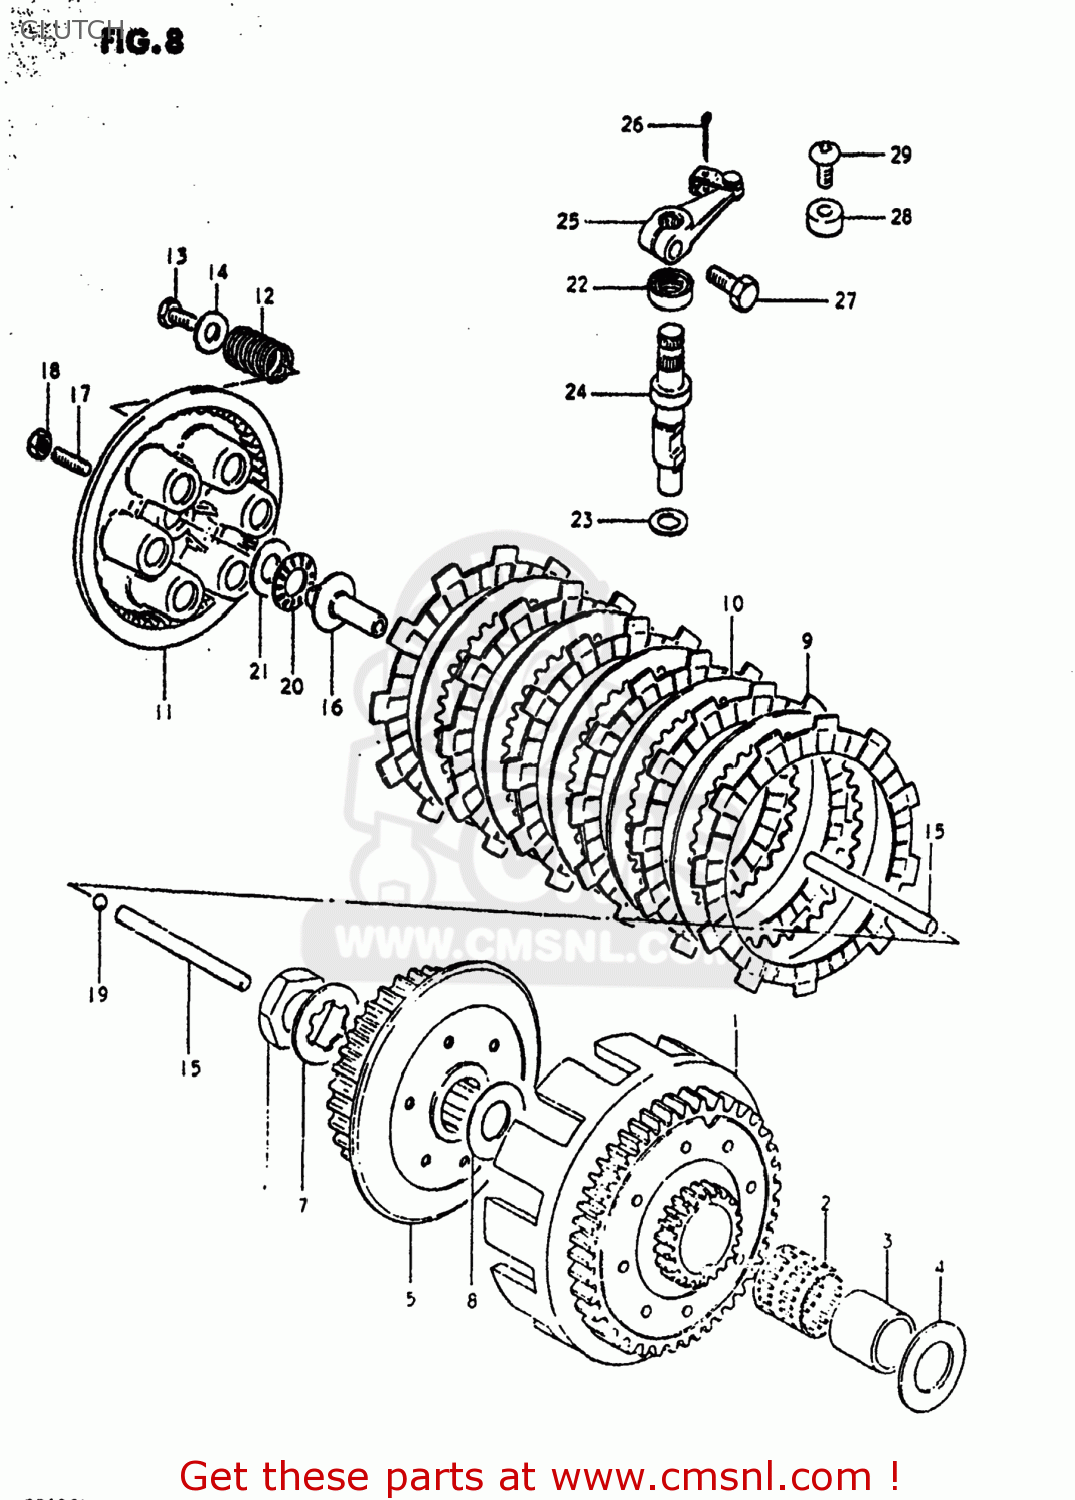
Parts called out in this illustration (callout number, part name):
1	GEAR ASSEMBLY,PRIMARY DRIVE
2	ROLLER BEARING (25X30X2
3	SPACER
4	WASHER(20X38X2)
5	HUB,CLUTCH SLEEVE
6	NUT (20MM)
7	WASHER,LOCK
8	WASHER(20X38X2)
9	PLATE,CLUTCH DRIVE (MCA)
10	PLATE,CLUTCH DRIVEN (NAS)
11	DISC,CLUTCH PRESSURE
12	SPRING
13	BOLT, UPPER
14	WASHER
15	ROD,CLUTCH PUSH
16	PIECE,CLUTCH PUSH
17	SCREW
18	NUT 6MM
19	BALL
20	BEARING(15X28X2)
21	WASHER
22	OIL SEAL
23	WASHER (14.2X22X1)
24	SHAFT,CLUTCH RELEASE C
25	ARM,CLUTCH RELEASE
26	PIN
27	BOLT
28	GUIDE,CLUTCH CABLE
29	SCREW
